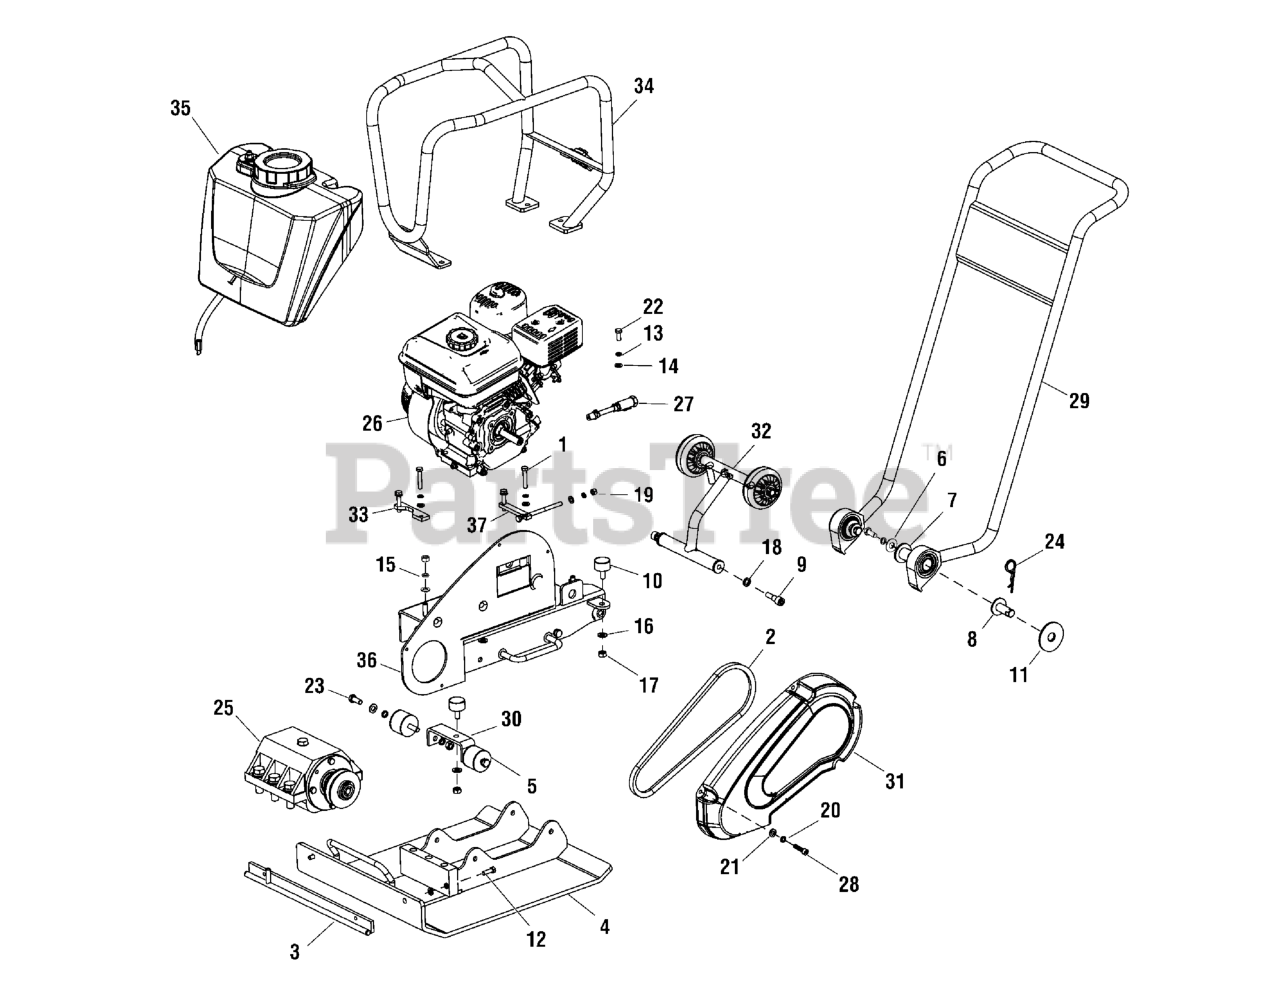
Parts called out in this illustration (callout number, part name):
1	BOLT, Hex, M8 x 45
2	V-BELT
3	WATER HOSE
4	BASE PLATE
5	VIBRATION MOUNT, Rubber
6	WASHER
7	BUSHING, Nylon
9	BOLT, Locking, Wheel Frame
10	HANDLE VIBRATION, Rubber
11	WASHER
12	BOLT, Hex, M8 x 25
13	WASHER, Spring
14	WASHER, Flat
15	WASHER, Spring
16	WASHER, Flat
17	NUT, Hex, M8
18	WASHER, Spring
19	NUT, Hex, M8
20	WASHER, Spring
21	WASHER, Flat
22	BOLT, Hex,
23	BOLT, Hex,
24	RETAINER RING
25	ECCENTRIC BOX ASSEMBLY
26	ENGINE ASSEMBLY
27	EXHAUST OIL ASSEMBLY
28	SCREW, Socket Head
29	HANDLE ASSEMBLY
30	BRACKET
31	BELT COVER
32	ROAD WHEEL FRAME ASSEMBLY
33	ENGINE FIXING PLATE
34	TANK GUARD ASSEMBLY
35	WATER TANK ASSEMBLY
36	ENGINE PLATE
37	ENGINE ADJUSTING PLATE
